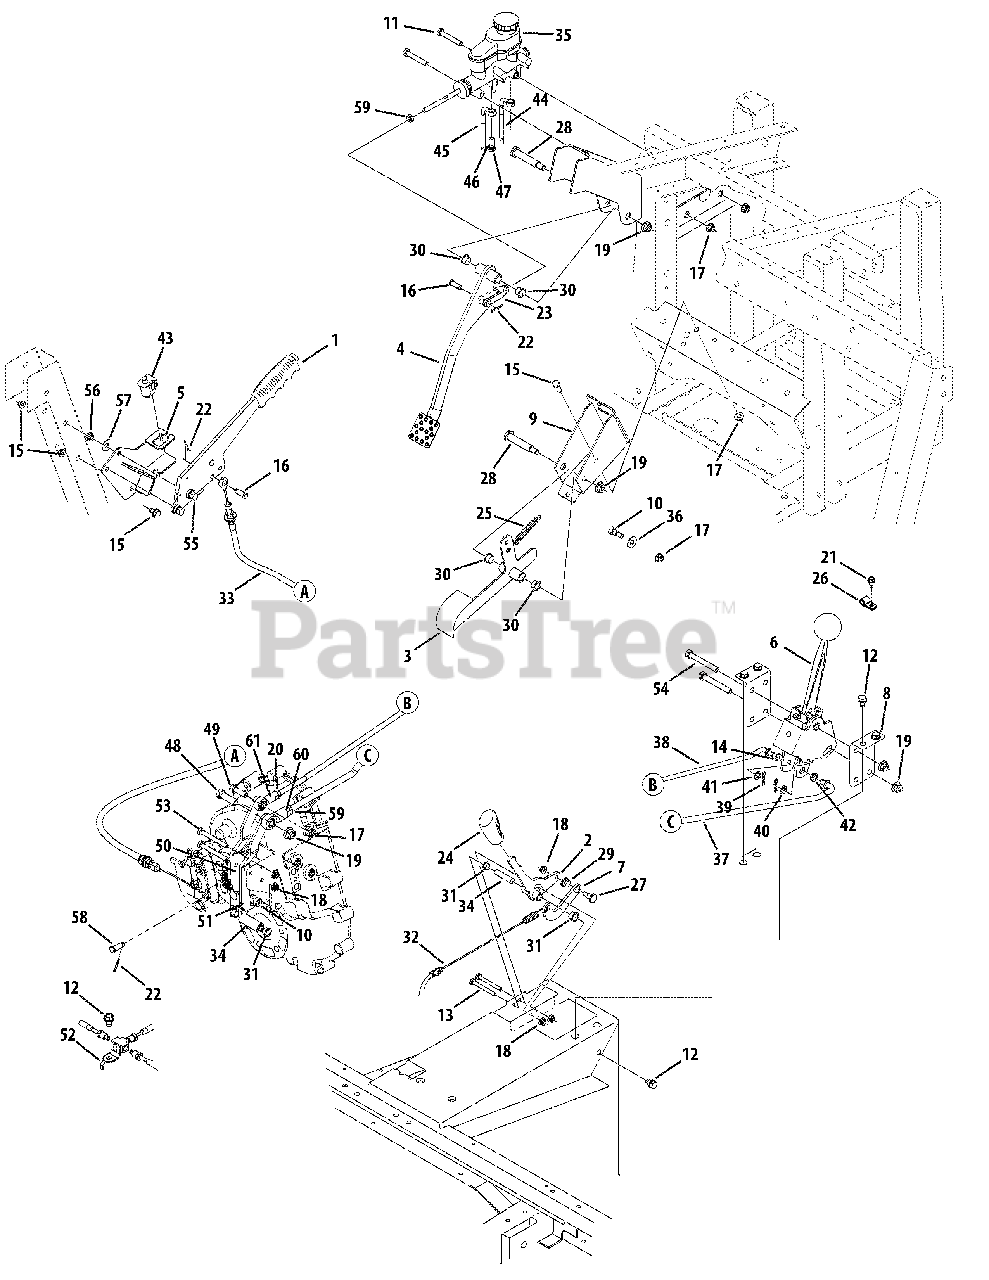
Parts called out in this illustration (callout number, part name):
1	Lever Assembly, Brake
2	Lever Assembly, Diff Lock
2	Lever Assembly, Diff Lock, Bench Seat
3	Pedel Assembly, Accel
4	Pedel Assembly, Brake
5	Brkt Assembly, Mt, Park Brake
6	Shift Assembly, Hurst, 4x4
6	Shift Knob Kit
6	Shift Assembly, Hurst, 4x2
7	Plt, Pawl, Over Center
8	Mt, Shift, Cnsol
9	Brkt, Mt, Accel Pedal
10	Screw, Shldr, .372 X .375, 5/16-18
11	Screw, 5/16-18, 2.00, Gr5, Patch
12	Screw, Tt, 5/16-18, 0.500
13	Screw, 1/4-20, 2.25, Gr5, Std
14	Brg., Flange, .315 ID
15	Screw, 5/16-18, .75, Gr5, Std
16	Pin, Clevis, 312 Od X 1.0"
17	Nut, Flglk, 5/16-18
18	Nut, Flglk, 1/4-20, Grf, Nylon
19	Nut, Flglk, 3/8-16, Grf, Nylon
20	Nut, Jam, 5/16-24, Gr5
21	Screwew, Tt, 1/4-20 x .500
22	Pin, Cot, 3/32, 1.0
23	Yoke, 5/16-24
24	Hndl, Selct
25	Spr, Extn, .38 Od X 3.6
26	Clamp, Hose
27	Screw, Shldr, .375x.380, 1/4-20
28	Screw, Shldr, .500 X 2.230, 3/8-16
29	Plastic Bushing .380 Id
30	Brg, Flg, Nyliner, .500idx.34lg
31	Brg, Flg, .375 X .580 X .250
32	Cable, Cont, Diff, Lock
33	Cable, Cont, Park, Brake
34	Spcr, Pivot, Diff Lock
35	Cyl, Master, Tandem
36	Wash, Flat, .349 X .879 X .063
37	Link, Shift, F N R
38	Link, Shift, Hi Lo, 4x4
39	Pin, Cotter, 1/16 x .75
39	Pin, Cotter, .072 Dia. x 1.13 Lg.
40	Wash, Flat, .385 X .62 X .063
41	Wash, Flat, .330 X .630 X .0635
42	Brg, Flg, .377 Id
44	Hose, Brake, Master Cyl, Front
45	Hose, Brake, Master Cyl, Rear
46	Ftg, Banjo Ftg Bolt, M10 x 1.00
47	Ftg, Banjo Ftg Crush Wash
48	Screw, 3/8-16 x 1.25
49	Screw, 5/16-18 x 1.25
50	Lever, Assembly, Shift, Hi-Lo, 4x4
51	Lever, Assembly, Shift, F N R
52	Ftg., Tee, -3, 45 Deg Flare
53	Screw, 1/4-20 x 2.50
54	Screw, 3/8-16 x 2.75
55	Screw, 5/16-18 x 2.00
56	Nut, Jam, 5/16-18
57	Washer, Flat, .344 x .688 x .065
58	Pin, Clevis
59	Nut, Jam, 3/8-24
60	Rod, End, 3/8 ID
61	Rod, End, 5/16 ID
